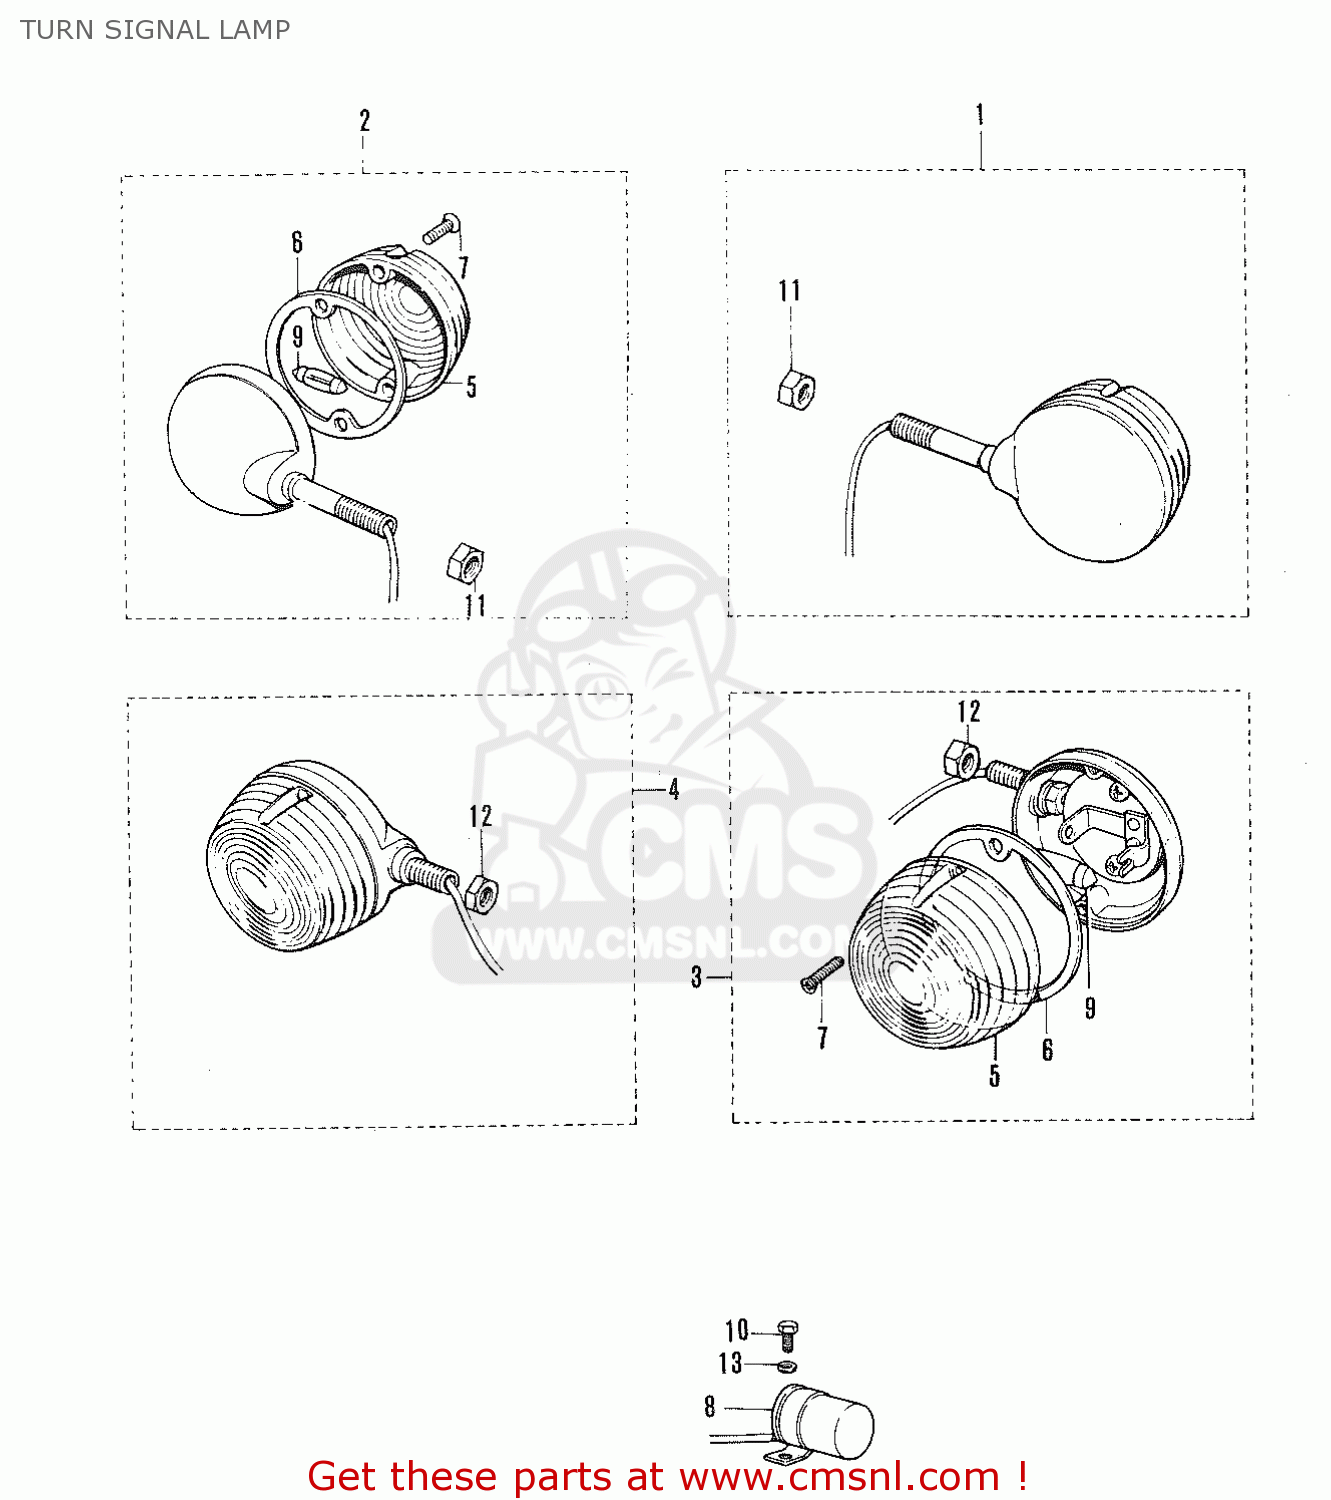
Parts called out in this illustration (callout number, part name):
1	LAMP ASSEMBLY,FRONT TURN SIGNAL
2	LAMP ASSEMBLY,FRONT TURN SIGNAL
3	LAMP ASSEMBLY,REAR TURN SIGNAL
4	LAMP ASSEMBLY,REAR TURN SIGNAL
5	LENS,TURNSIGNAL
6	GASKET,TURNSIGNAL LENS (NAS)
7	SCREW
8	TURN SIGNAL RELAY ASS'Y
9	BULB 6V 8W
10	BOLT
11	NUT
12	NUT
13	LOCK WASHER
